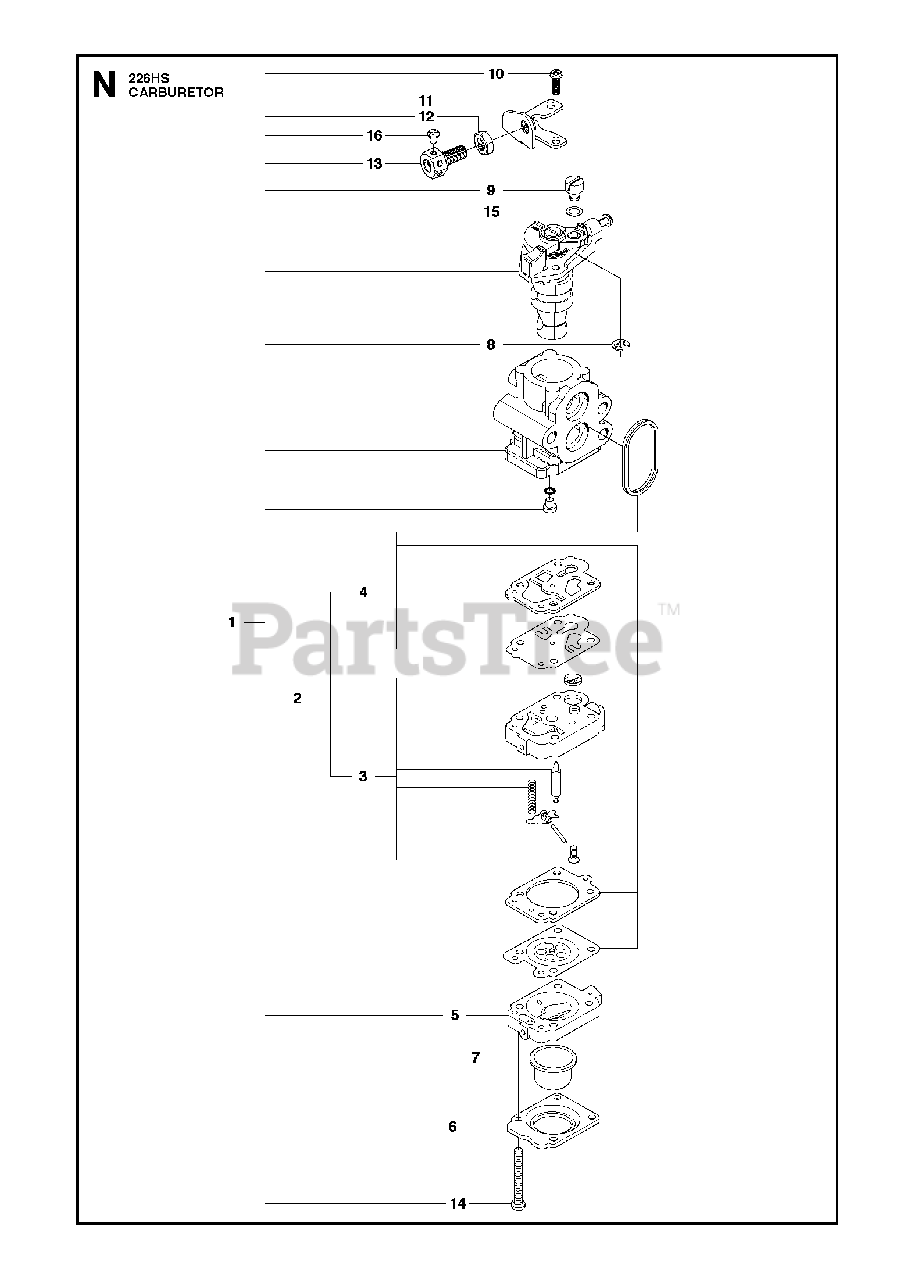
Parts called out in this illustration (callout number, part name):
1	CARBURETOR ASSY
2	REBUILD KIT
3	CARBURETOR BODY
4	GASKET KIT
5	BODY
6	1OVER
7	PUMP
8	RING
9	SWIVEL
10	SCREW
11	BRACKET
12	NUT
13	SCREW CABLE ADJUST
14	SCREW
15	BRACKET
16	SCREW
